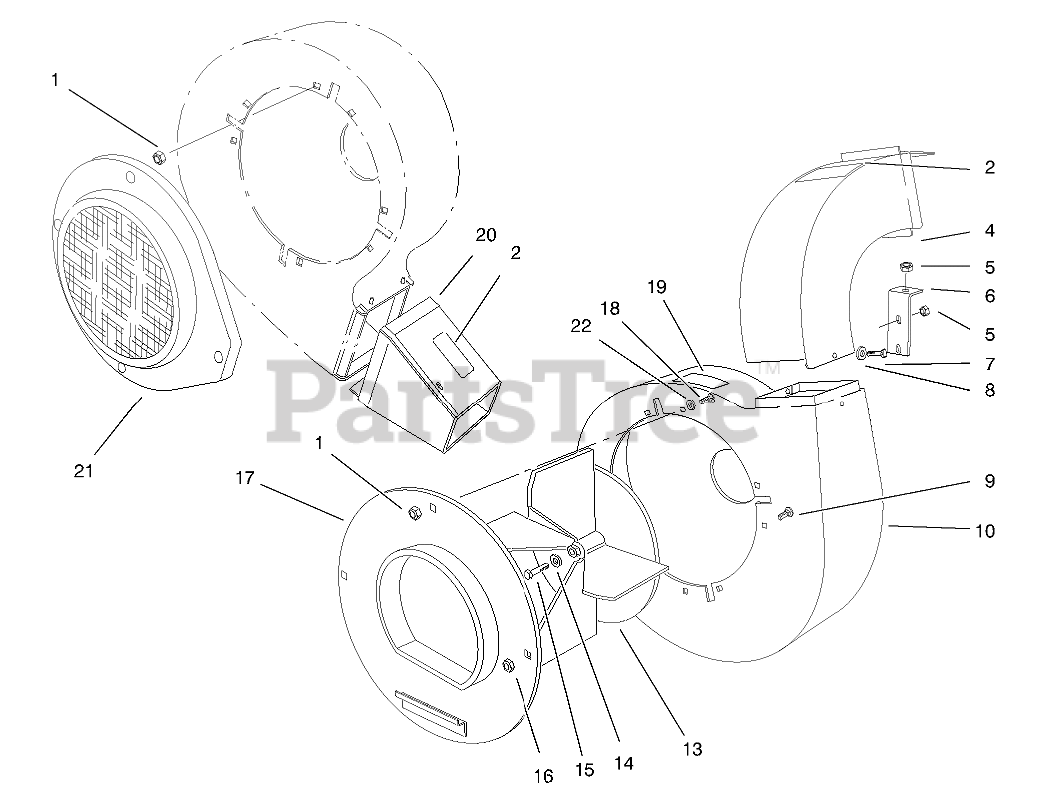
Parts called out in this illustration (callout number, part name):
1	NUT-FLANGE
2	DECAL-CAUTION, BAG
4	Chute-Vacuum
5	NUT-LOCK, NI
6	Bracket-Housing
7	SCREW-HH
8	WASHER-BELLEVILLE
9	SCREW-CARR
10	Blower Housing
13	Fan Assembly
14	WASHER-BELLEVILLE
15	SCREW-HH
16	NUT-LOCK, NI
17	Blower Cover
18	BOLT-CARR
19	Decal-Warning
20	Blower-Exhaust
21	INTAKE-BLOWER
22	WASHER-FLAT
